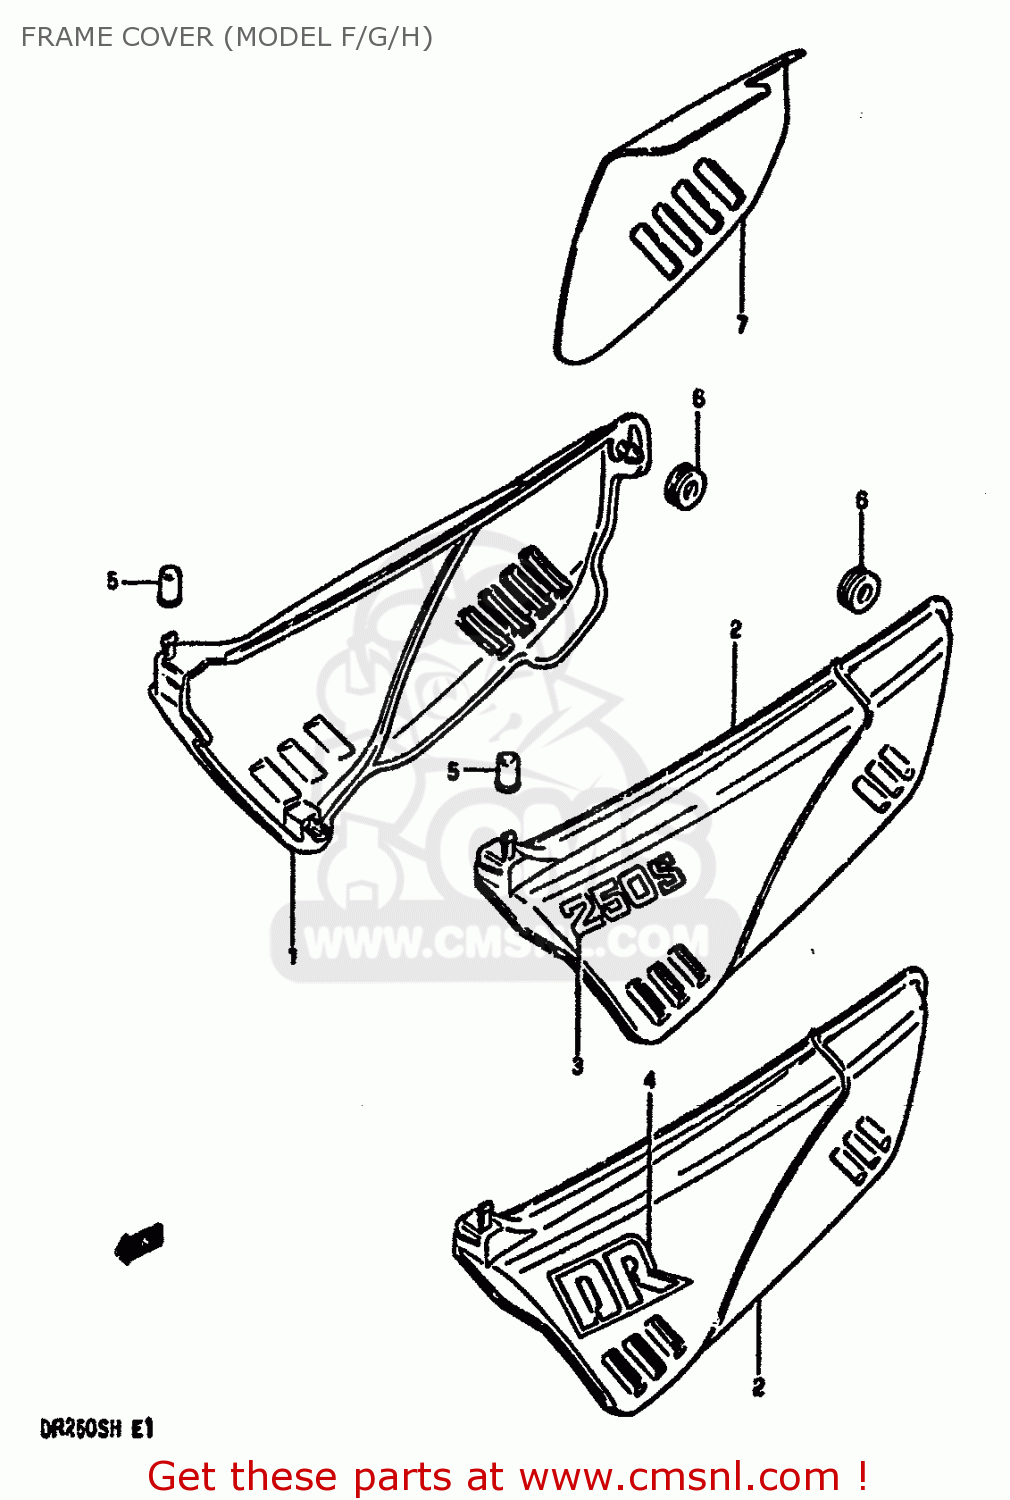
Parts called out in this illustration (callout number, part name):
1	COVER,FRAME RH (BLUE)
2	COVER,FRAME LH (BLUE)
3	EMBLEM
4	EMBLEM
5	CUSHION
6	CUSHION
7	HEAT SHIELD,FRAME COVER
